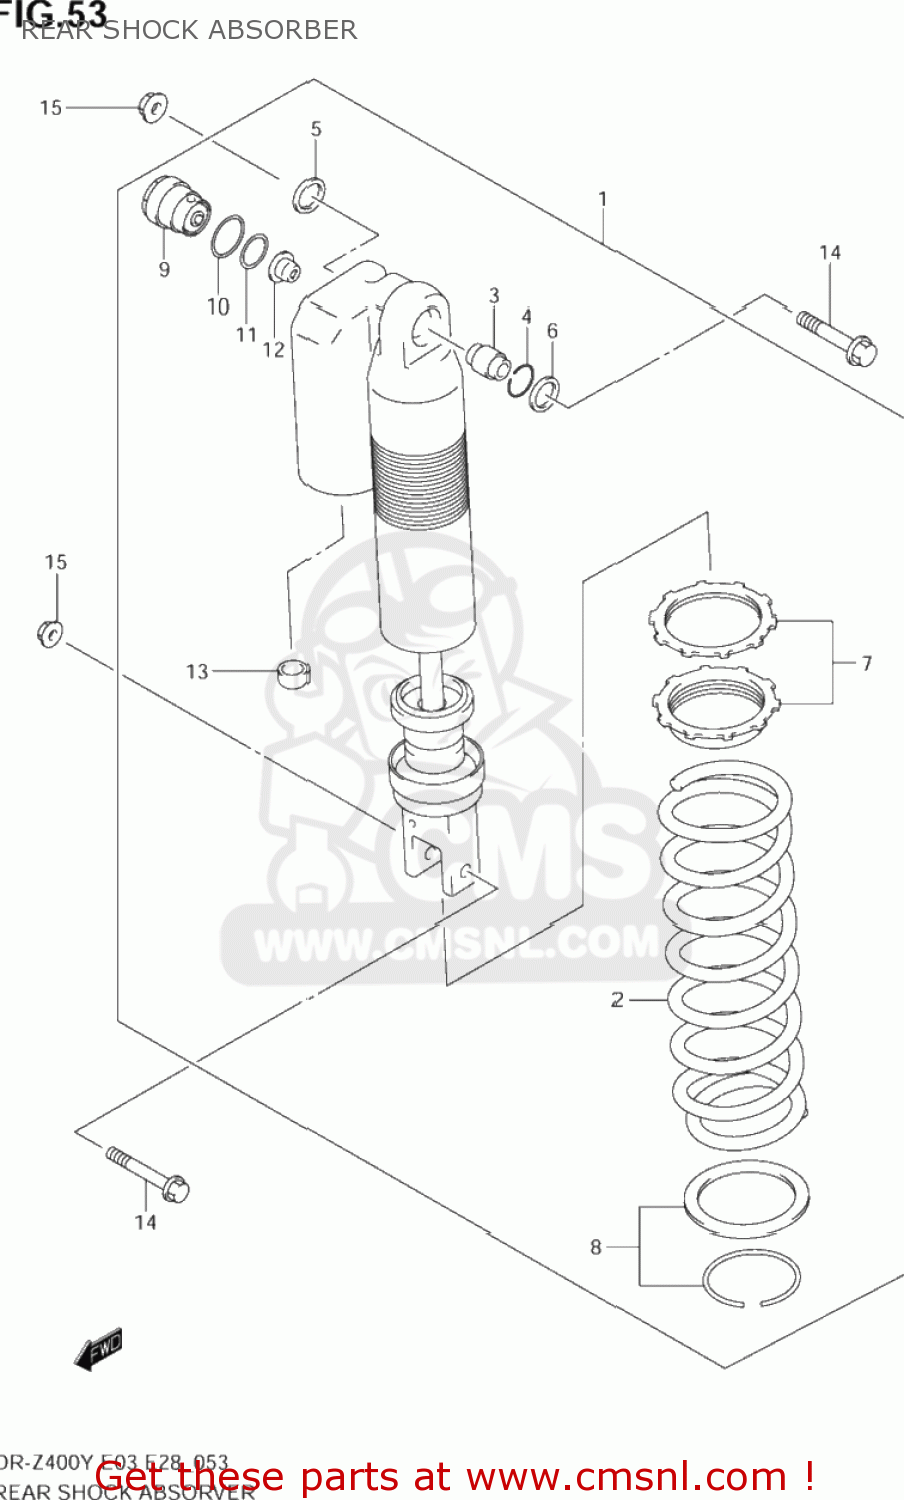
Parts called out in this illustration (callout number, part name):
1	ABSORBER ASSY,RR SHOCK
2	SPRING,RR(SOFT)
3	BEARING,RR SHOCK ABSORBER
4	RING,STOPPER
5	SEAL,DUST UPR,R
6	SEAL,DUST UPR,L
7	ADJUSTER SET
8	SPRING SEAT SET
9	BOLT,PLUG
10	O RING
11	O RING,CTR BOLT UPR
12	COLLAR,ORIFICE
13	CAP,AIR VALVE
14	BOLT(10X47.5)
15	NUT
